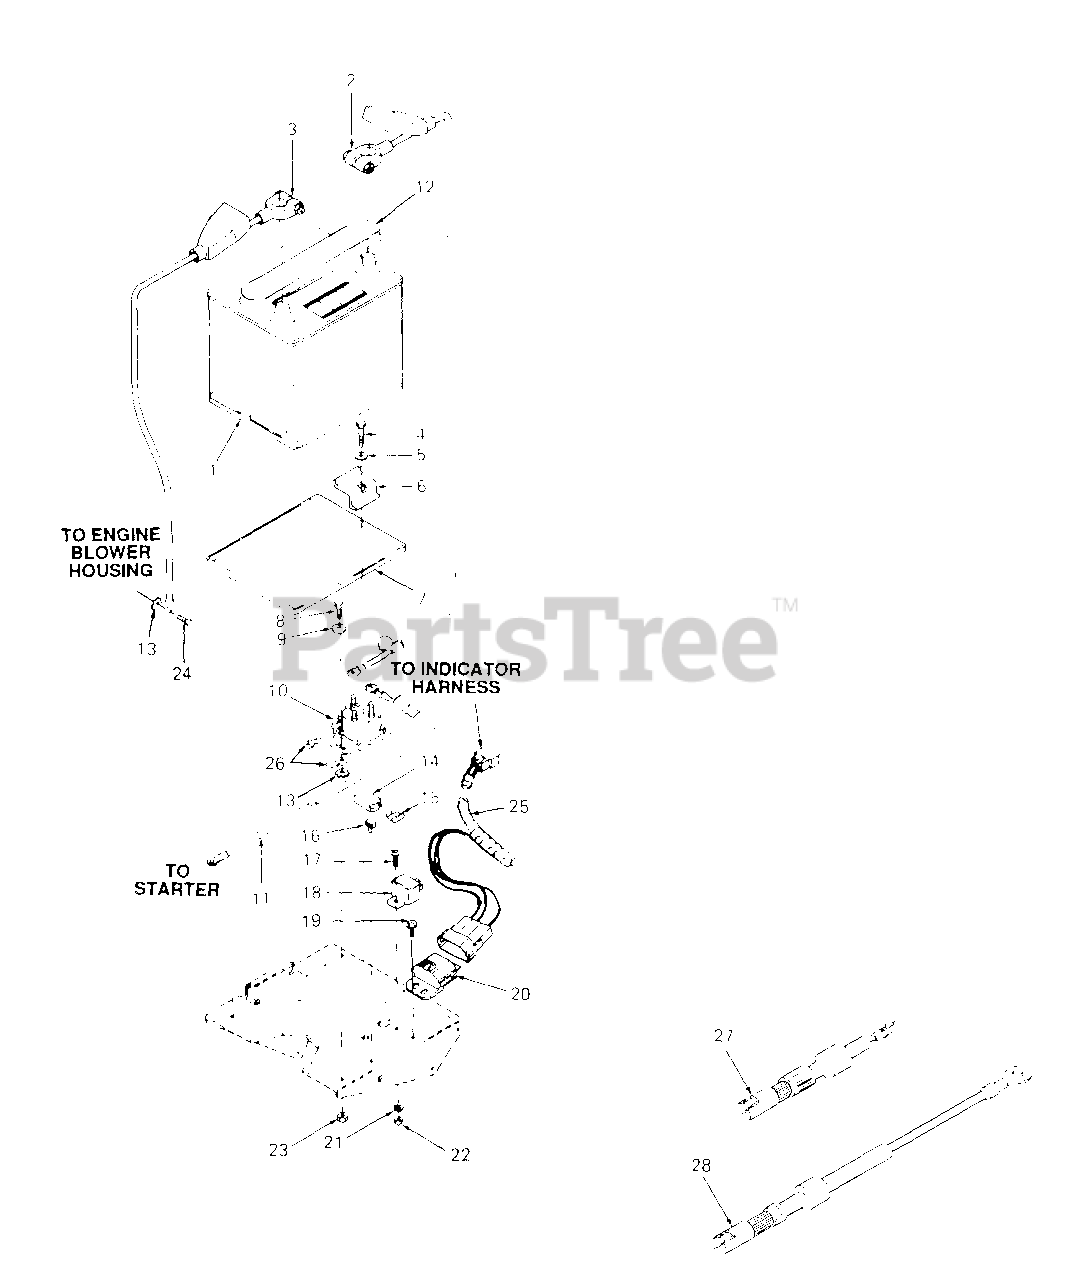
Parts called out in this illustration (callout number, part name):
1	Battery
2	Cable, Positive Battery
3	Cable, Negative Battery
4	Screw, Hex Cap, 5/16-18 X 1.38 Lg
5	Washer, Flat, .34 X .68 X .062 Thk
8	Screw, Hex Cap, 1/4-20 X .62 Lg GR5
9	Washer, Bell, .265 X .75 X .062 Thk
10	Solenoid
11	Cable, Starter
12	Cap, Battery Vent
13	Washer, Int-Ext, 1/4
14	Holder, Fuse
15	Fuse, 20 Amp
16	Clip, Fuse Holder Mtg
17	Screw, Truss Mach, #10-24 X .50 Lg
18	Relay
19	Screw, Hex Wash HD TT, 1/4-20 X .50 Lg
20	Module, Voltage Sensor
21	Washer, Lock, #10
22	Nut, Hex, #10-24
23	Nut, Hex Center Lock, 1/4-20
24	Screw, Sems
25	Main Harness
26	Lug, Quick Connect
27	Diode Assy
28	Diode Assy w/Lead
